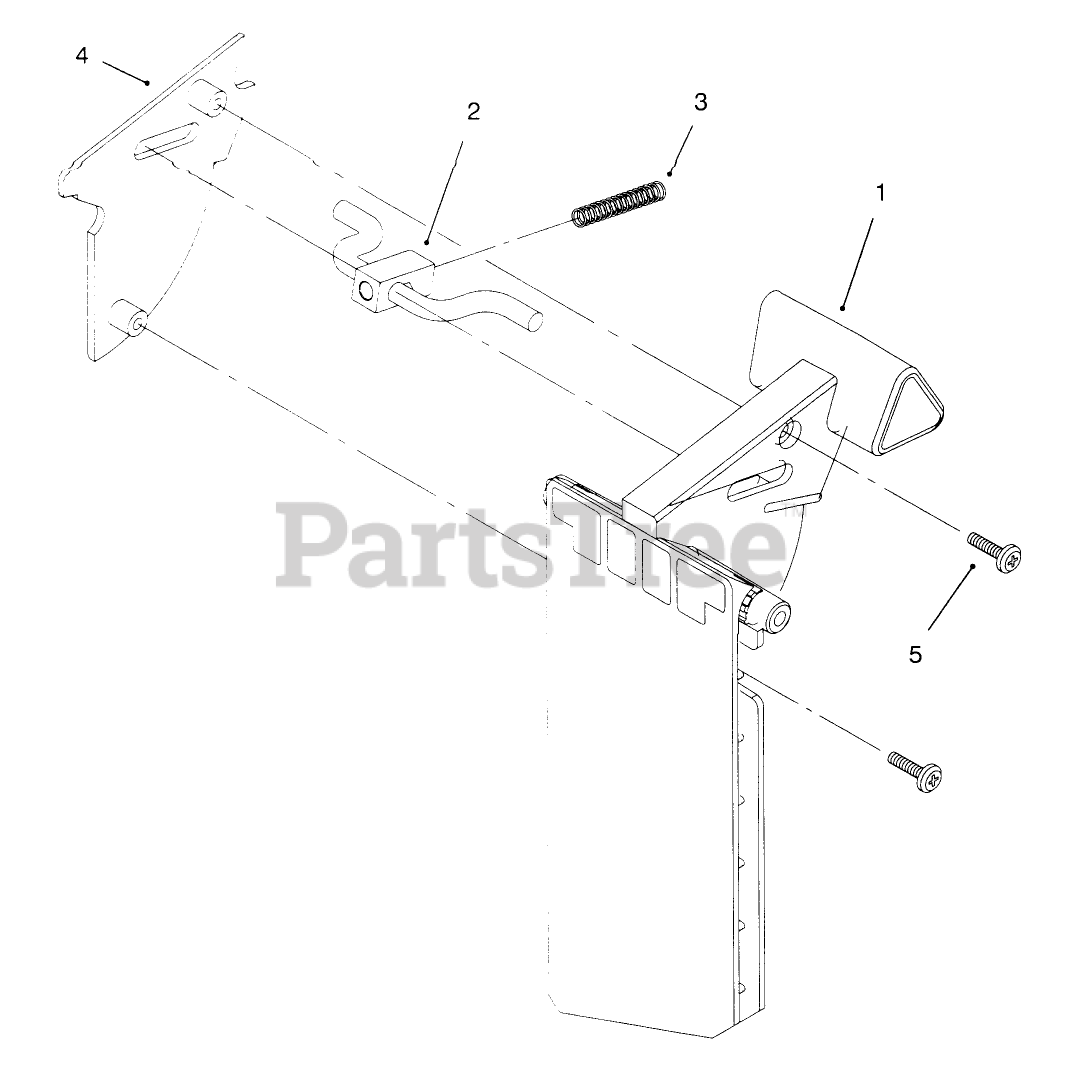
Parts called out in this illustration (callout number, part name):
1	DOOR-DISCHARGE
2	LATCH-DOOR
3	SPRING-COMPRESSION, LATCH
4	DOOR COVER
